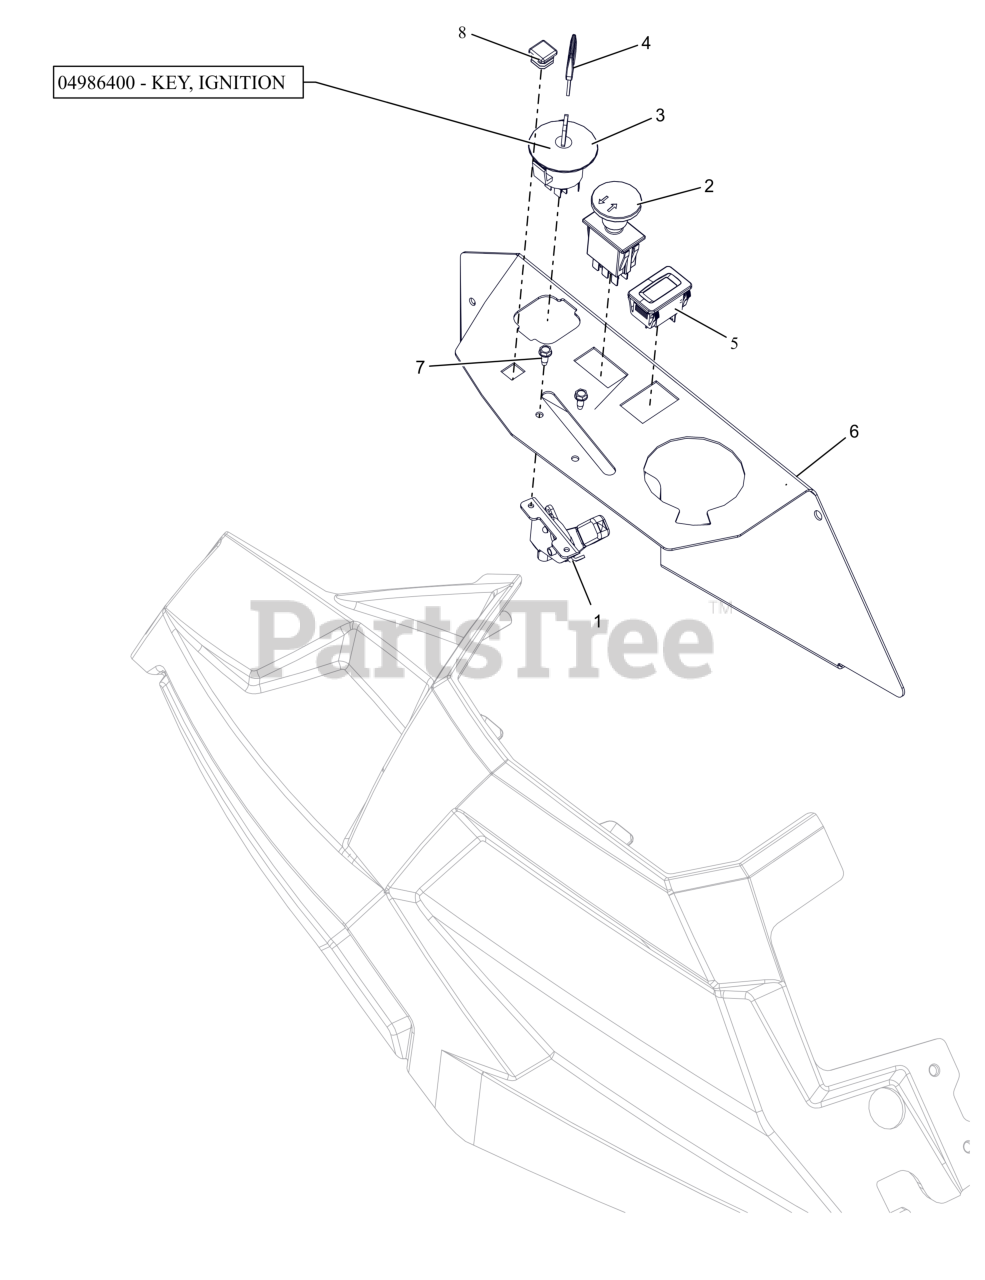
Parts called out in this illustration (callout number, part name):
1	CABLE - THROTTLE CONTROL
2	SWITCH, CLUTCH (YELLOW)
3	KEYSWITCH-IGNITION 4 POS
4	KEY, IGNITION
5	HOUR METER
6	PANEL, CONTROL (RED)
7	SCR,TAP #10-24X.50 HWH TR ZCC
8	PLUG, 5/8" SQ BLACK (14-20GA)
